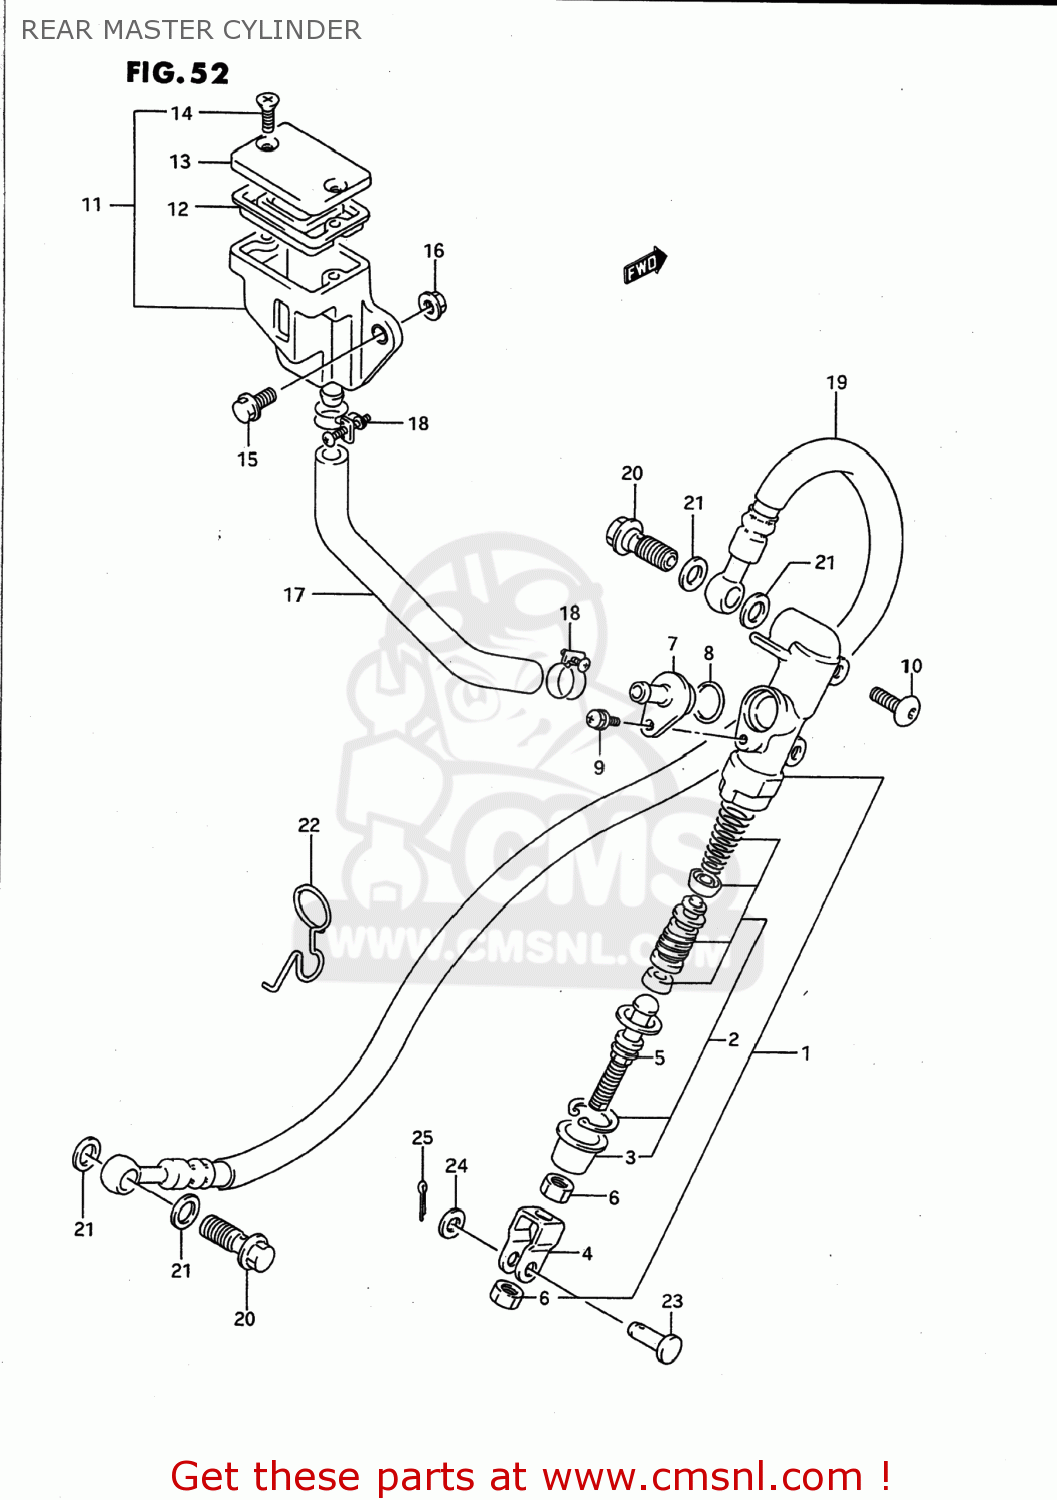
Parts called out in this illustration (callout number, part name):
1	CYLINDER ASSY,RR MASTER
2	PISTON/CUP SET
3	BOOT
4	YOKE
5	ROD,PUSH
6	NUT
7	CONNECTOR
8	O RING
9	SCREW
10	BOLT(6X21)
11	TANK ASSEMBLY,RESERVOIR
12	DIAPHRAGM
13	CAP
14	SCREW
15	BOLT
16	NUT
17	HOSE,RESERVOIR TANK
18	CLIP
19	HOSE,RR BRAKE
20	BOLT UNION
21	WASHER(10X15X1.5)
22	GUIDE,RR BRAKE HOSE
23	PIN
24	WASHER
25	PIN
